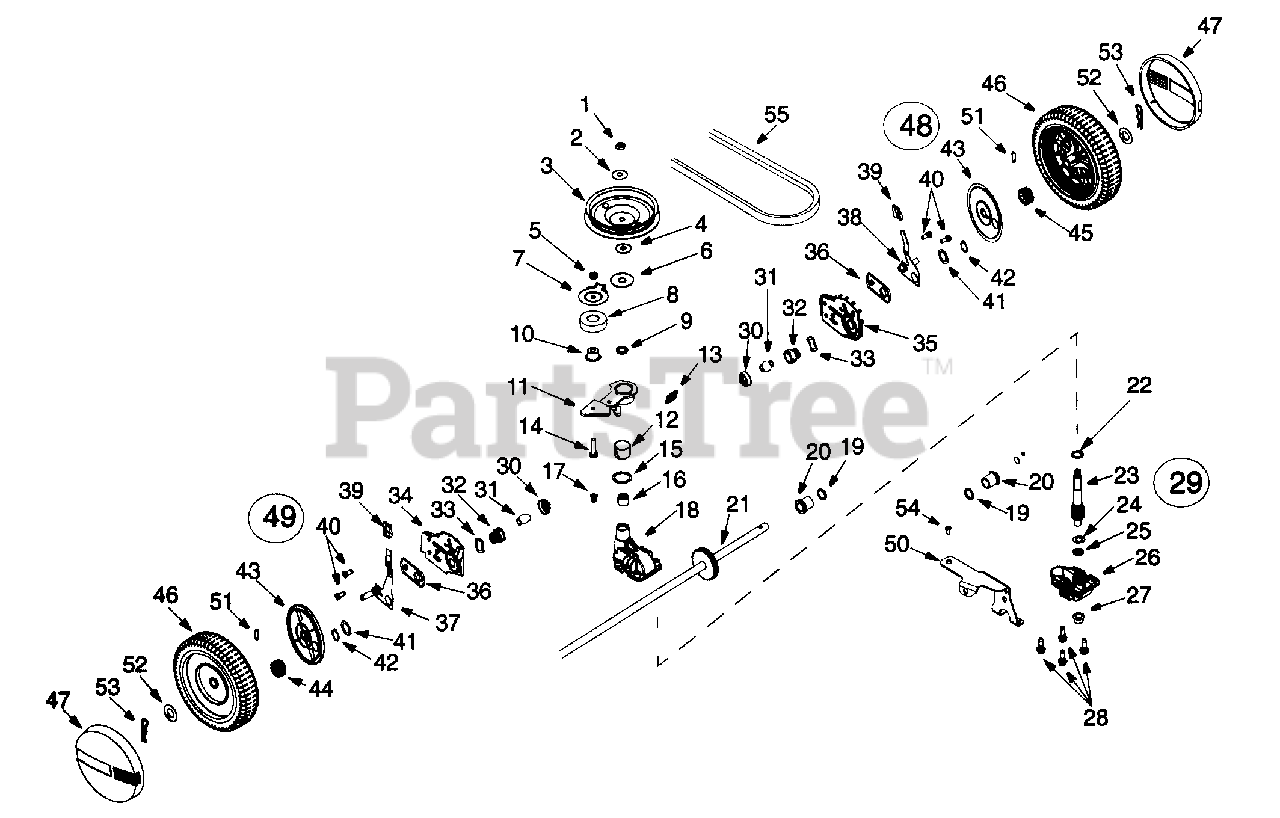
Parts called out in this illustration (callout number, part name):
1	Hex Jam Nut 5/16-24
2	Bell Wash .325 x .930 x .045
3	Pulley
4	Bell Wash .325 x .930 x .045
5	Hex Nut 1/4 - 28 Lock
6	Flat Wash .442 x 1.38 x .060
7	Belt Keeper
8	Ball Bearing
9	Oil Seal
10	Flange Spacer
11	Idler Bracket Assembly
12	Bearing Sleeve
13	Wash:Flat: .504 x .700 x .030
14	Hex Cap Screw 1/4-28 x 1.00 Gr. 5
15	Flat Washer .865 x 1.145 x .030
16	Needle Bearing .438 x .625 x .500
17	Plug 1/4 x .437
18	Housing Asm:Upper:
19	Seal:Oil: .500 x .687 x .094
20	Flange Bearing .503 x .689 x .792
21	Output Shaft
22	Flat Washer .504 x .700 x .030
23	Pinion Shaft 10T.
24	Thrust Washer .375 x .70 x .030
25	Thrust Washer .388 x .625 x .062
26	Housing:Lwr:
27	Flange Bearing .378 x .531 x .370
28	Hex Screw w/Wash 1/4-20 x .750
29	Transmission-Complete
30	Bearing Retainer
31	Bearing Sleeve .50 I.D.
32	Bearing Support
33	Wave Washer 1.5 x 1.0 x .029
37	Front Lever R.H.
38	Front Lever L.H.
39	Knob
40	Hex Cap Screw 3/8-16 x .75
41	Washer DD 1.5" O.D.
42	Snap Ring 1.0 Dia
43	Wheel Dust Cap
44	Gear 14T RH Fwd
45	Gear 14T LH Fwd
46	Whl 8x1.75 Disk Bar Gray Sleeve S
47	Hubcap:Whl:Radial Spoke Grey
48	Height Adj. Complete RH
49	Height Adj. Complete LH
50	Cable Idler Bracket
51	Dowel Pin
52	Flat Washer 1/2 x 1.00 x .063
53	Cotter Pin .08 x 1.42
54	Screw, Shoulder .375 x .25AB: 1/4-20
55	"V"-Belt
